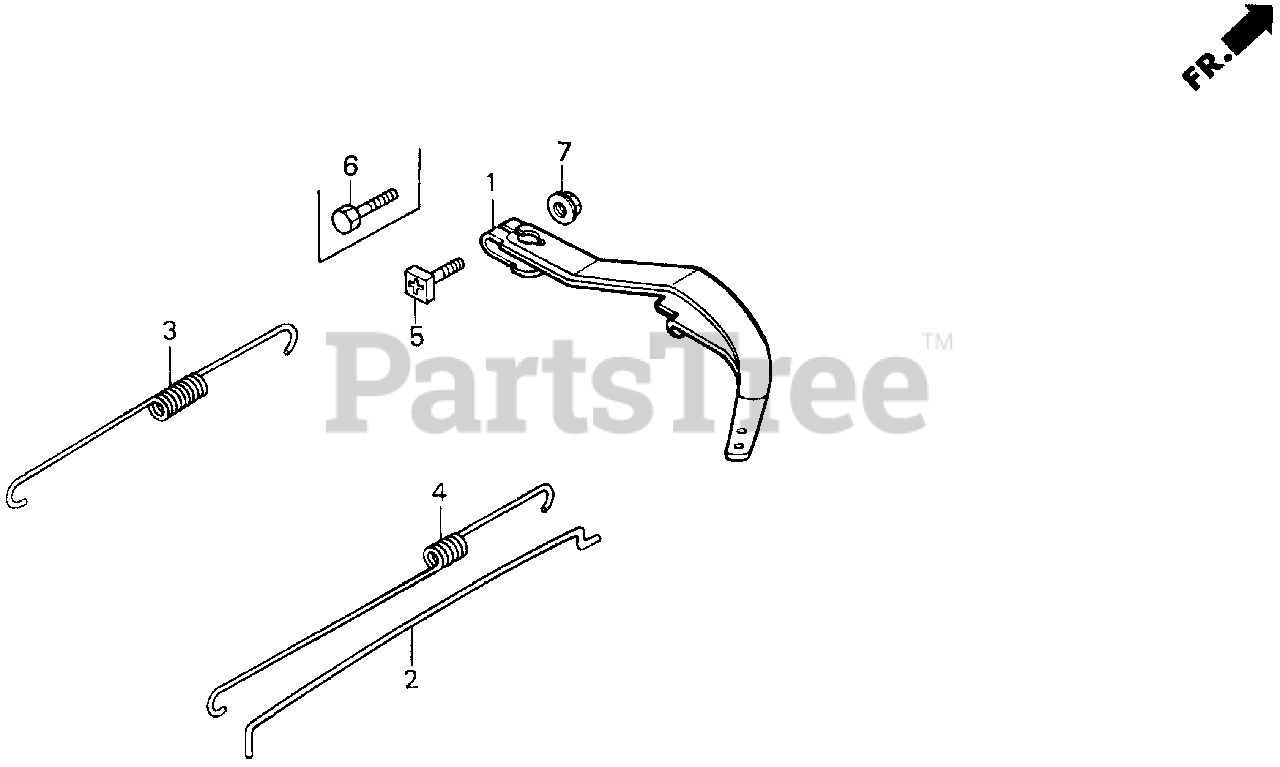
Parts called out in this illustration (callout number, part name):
1	ARM, GOVERNOR
2	ROD, GOVERNOR
3	SPRING, GOVERNOR
4	SPRING, THROTTLE RETURN
5	BOLT, GOVERNOR ARM
6	BOLT, HEX. (6X20)
7	NUT, FLANGE (6MM)
